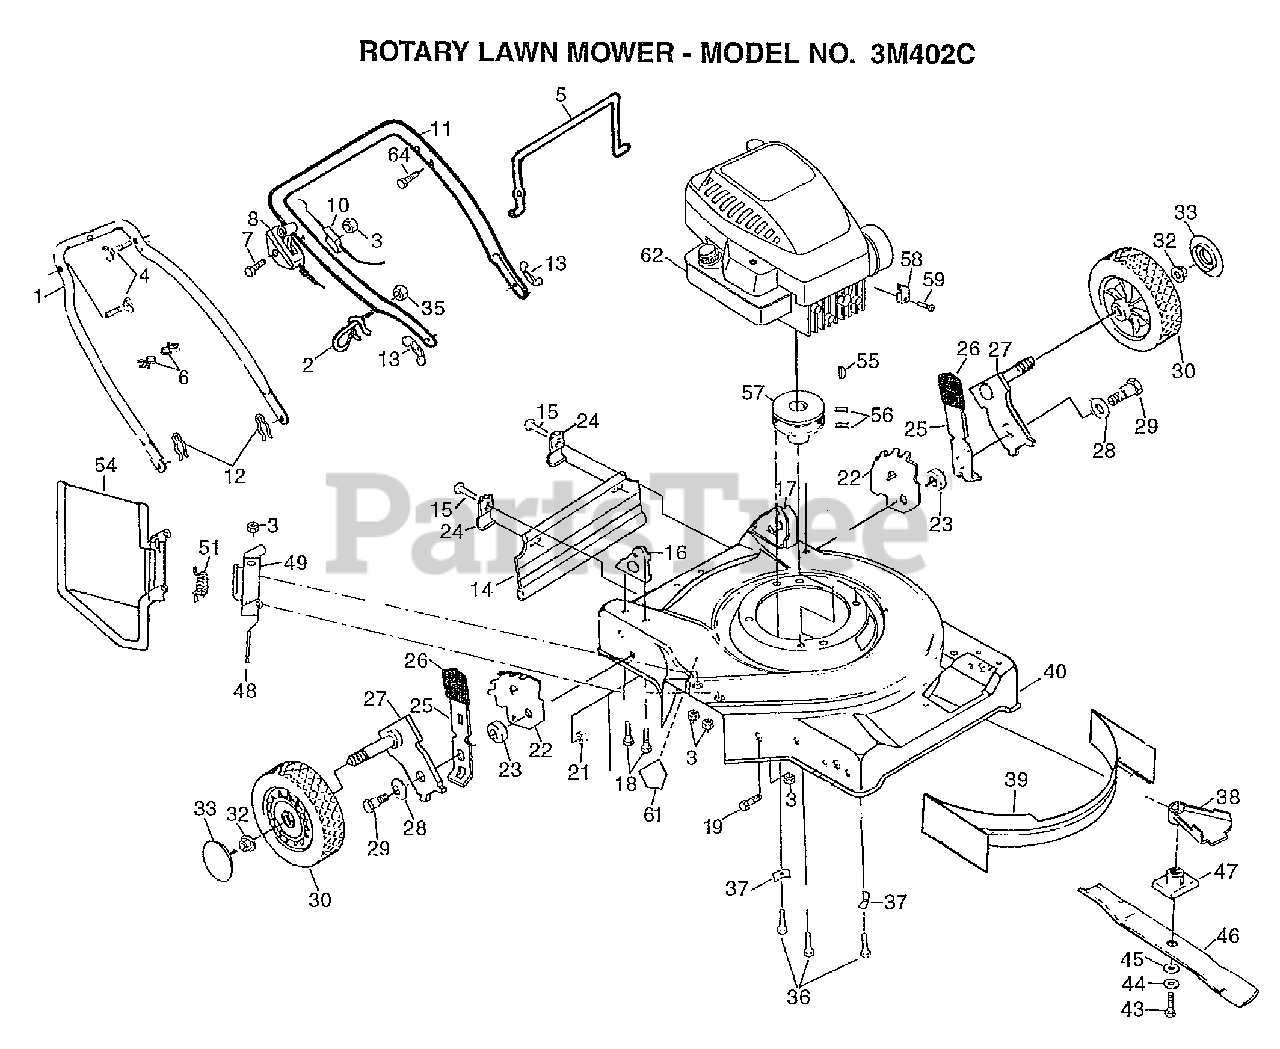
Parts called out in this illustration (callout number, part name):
2	ROPE GUIDE
4	BOLT.HANDLE.LM
5	BAIL.CNTRL.STD.BL
7	SCREW.HXHD.WASH.
8	CONTROL.THL.49.35
10	"CABLE,ENG ZONE CO"
12	HAIRPIN COTTER
13	"NUT,WING PM"
14	SKIRT.REAR.FGD.22
15	TAPPING SCREW
16	HDLE BRKT ASSY.RH
17	HDLE BRKT ASSY LH
18	SCREW 5/16-18X3/4
19	SCREW
21	LOCKNUT PM
22	BRACKET.ADJ.9POS.
23	SPACER.HEIGHT.ADJ
24	"BRKT,DEFL PM"
25	SPRING SELECTOR
26	KNOB PM
27	ARM.AXLE.ASM.BZP.
28	"WASHER, BELLEVIL."
29	BOLT SHLD 3/8-16
30	WHEEL.8X2.PR.RAD.
32	HEX FLANGE LOCKNT
33	HUB CAP
35	NUT
36	BOLT.ENG.3/8-16
39	BAFFLE FRONT 22SD
40	KIT.HSG.22SD.FWGD
43	SCREW
44	LOCKWASHER
45	"WASHER,HARDEN"
46	"BLADE.MULCH.22"""
47	ADAPTOR.BLADE.LM
48	ROD.HINGE.COMBI-C
49	BRACKET.HINGE.W/F
51	SPRING.HINGE
54	GUARD.DISCH.22SD.
55	HI PRO KEY PM
56	SCREW
57	ENGINE.PULLEY.FWG
58	CABLE CLAMP
59	SCREW PM
61	DECAL HYT
65	MULCHER PLUG
66	MULCHER BAIL
67	LATCH.BAIL.MULCH.
